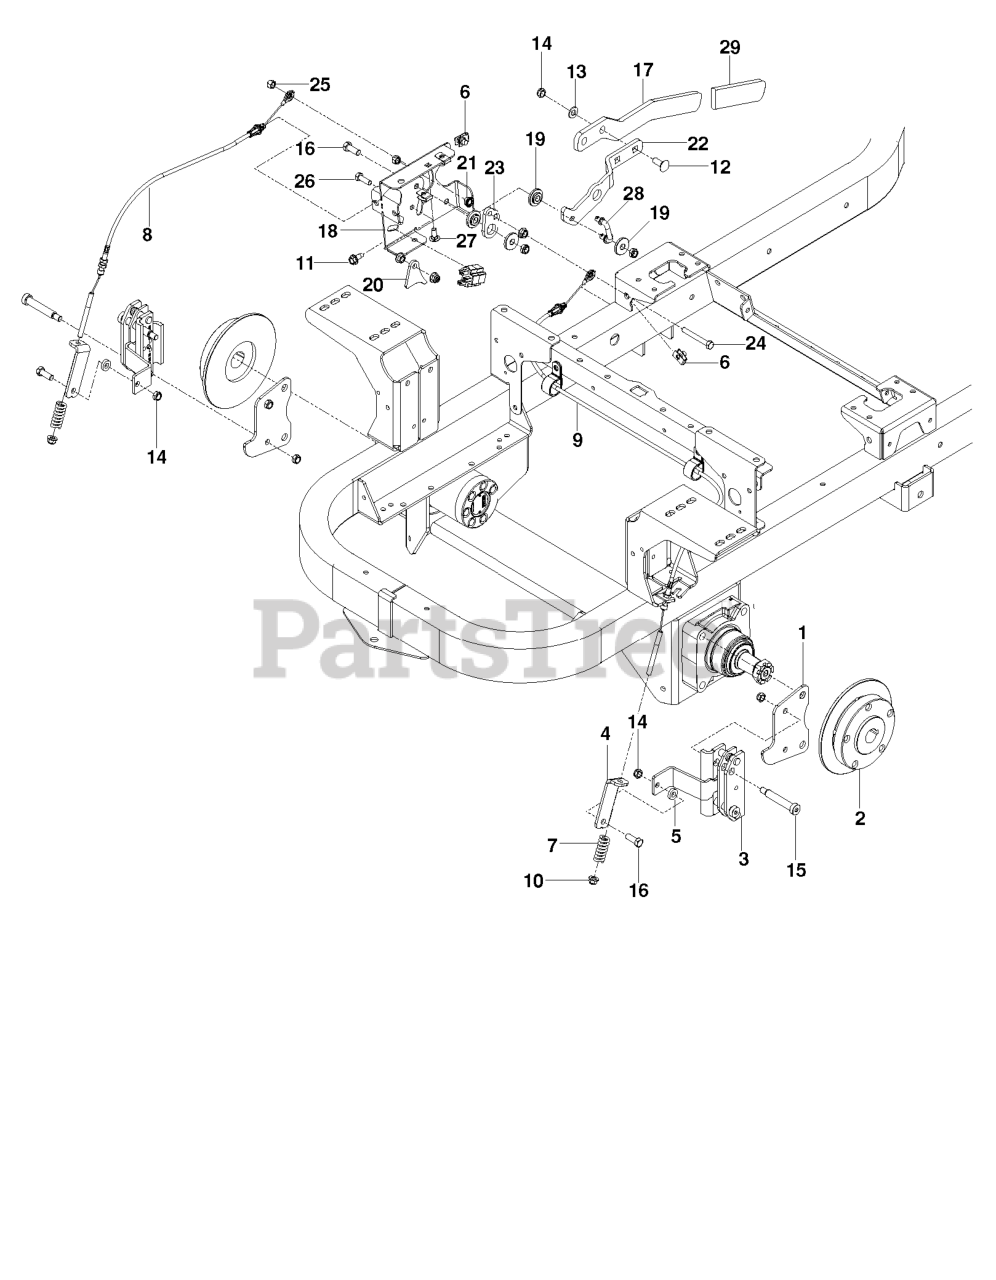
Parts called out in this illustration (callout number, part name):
1	PLATE, BRAKE
2	HUB, 5 BOLT
3	CALIPER PARK BRAKE
4	BRACKET, L
5	WASHER 3/8 X 3/4 X .187 TK
6	U-CLIP 5/16-18 NUT RETAINER
8	CABLE, BRAKE, SHORT
9	RP_CABLE, BRAKE, LONG
10	5/16-18 NYLOC FLANGE NUT
11	BOLT 5/16-18 X 3/4
12	RHSNB 3/8C X 1
13	WASHER 3/8 SAE FLAT
14	NUT HEX 3/8-16 NYLON, THIN
15	SB 3/8-16 X 2-1-1/2 SKT HDD ZD
16	HCS 3/8-16X1.GRD.5.ZD
17	ARM, BRAKE
18	MOUNT, BRAKE WLDMT
19	BUSHING, BRAKE
20	ACTUATOR, SWITCH
21	NUT 5/16C WHIZ
22	LEVER, BRAKE
23	BELLCRANK, BRAKE
24	HCS 5/16-18 X 2 1/2 TPBLT
25	NUT 5/16 NYLOC
26	HCS 5/16C X 1
27	BOLT 5/16C X 3/4" CARRIAGE
28	LINKAGE, BRAKE
29	GRIP, PARK BRAKE
